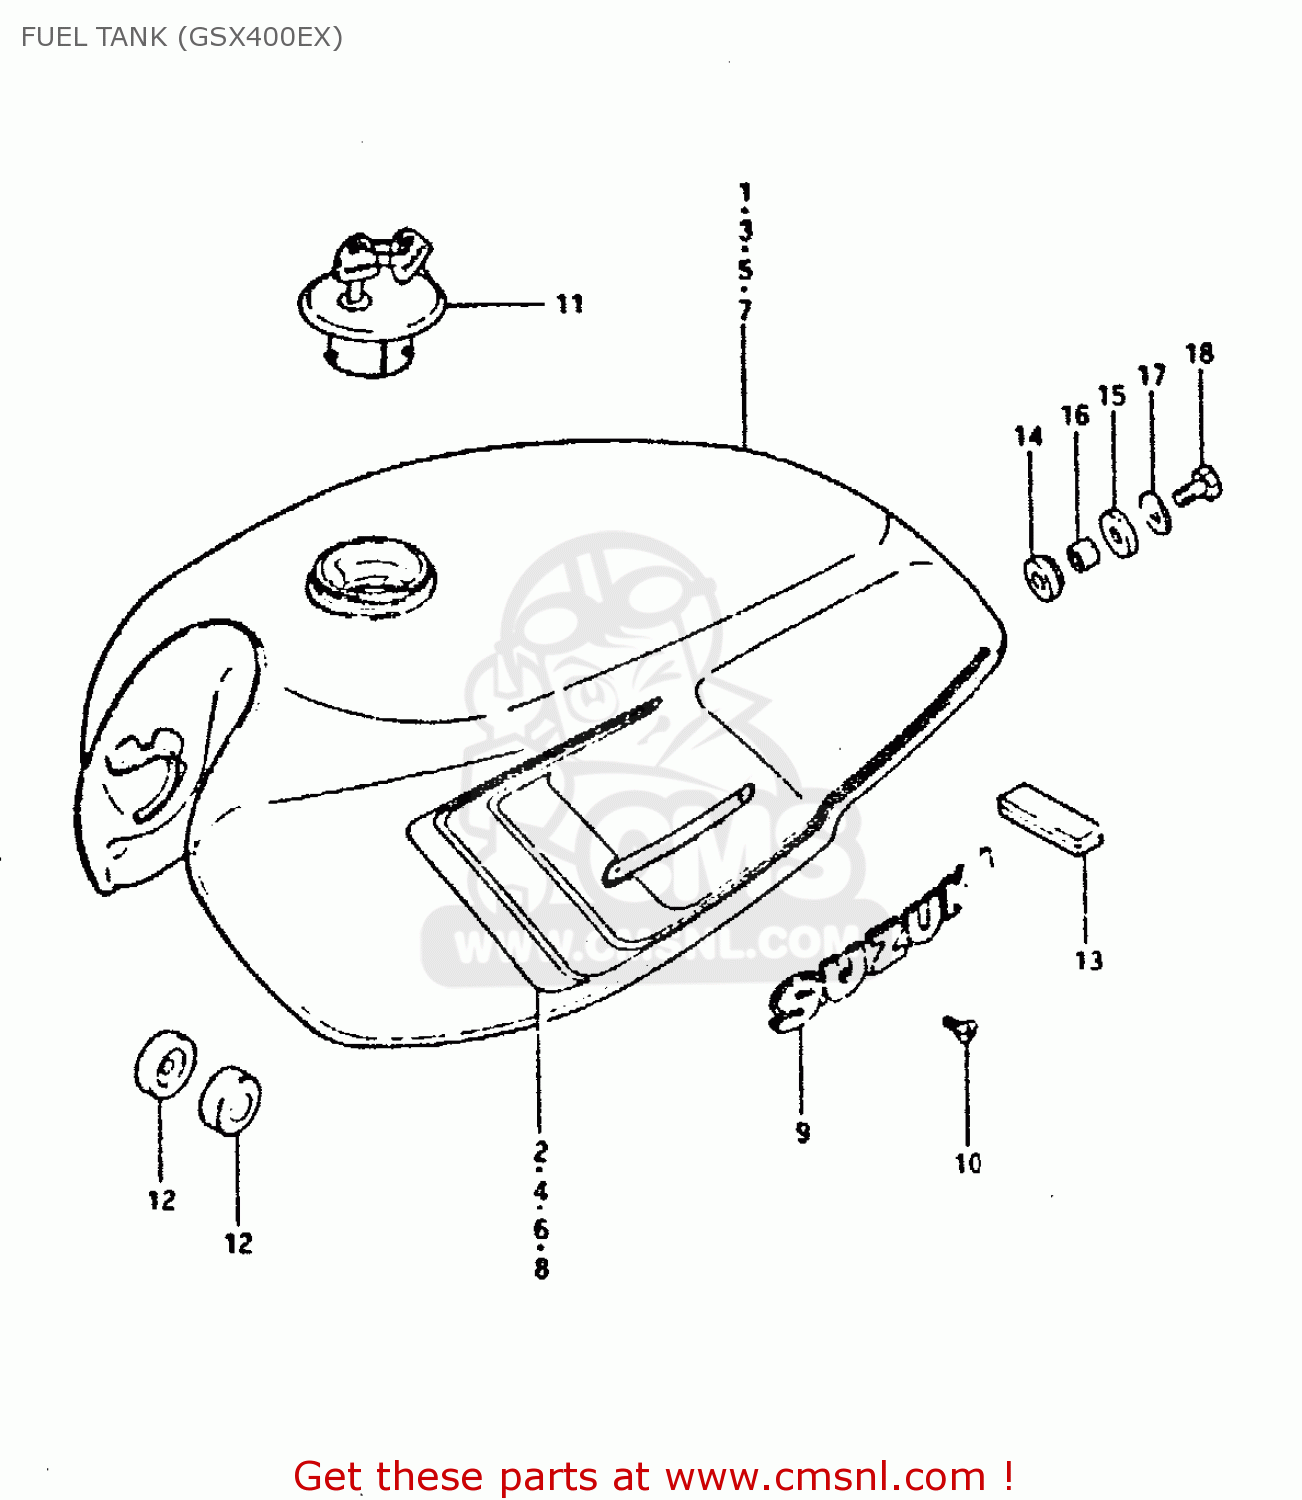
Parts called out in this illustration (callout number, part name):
1	TANK, FUEL (BLACK)
2	TAPE SET
3	TANK, FUEL (BLUE)
4	TAPE SET
5	TANK, FUEL (RED)
6	TAPE SET
7	TANK, FUEL (SILVER)
8	TAPE SET
9	EMBLEM
10	SCREW 3X6
11	CAP SET,FUEL TANK
12	CUSHION
13	CUSHION
14	CUSHION
15	CUSHION
16	SPACER(8.5X12X19)
17	WASHER (8.5X29X1.6)
18	BOLT (8X30)
